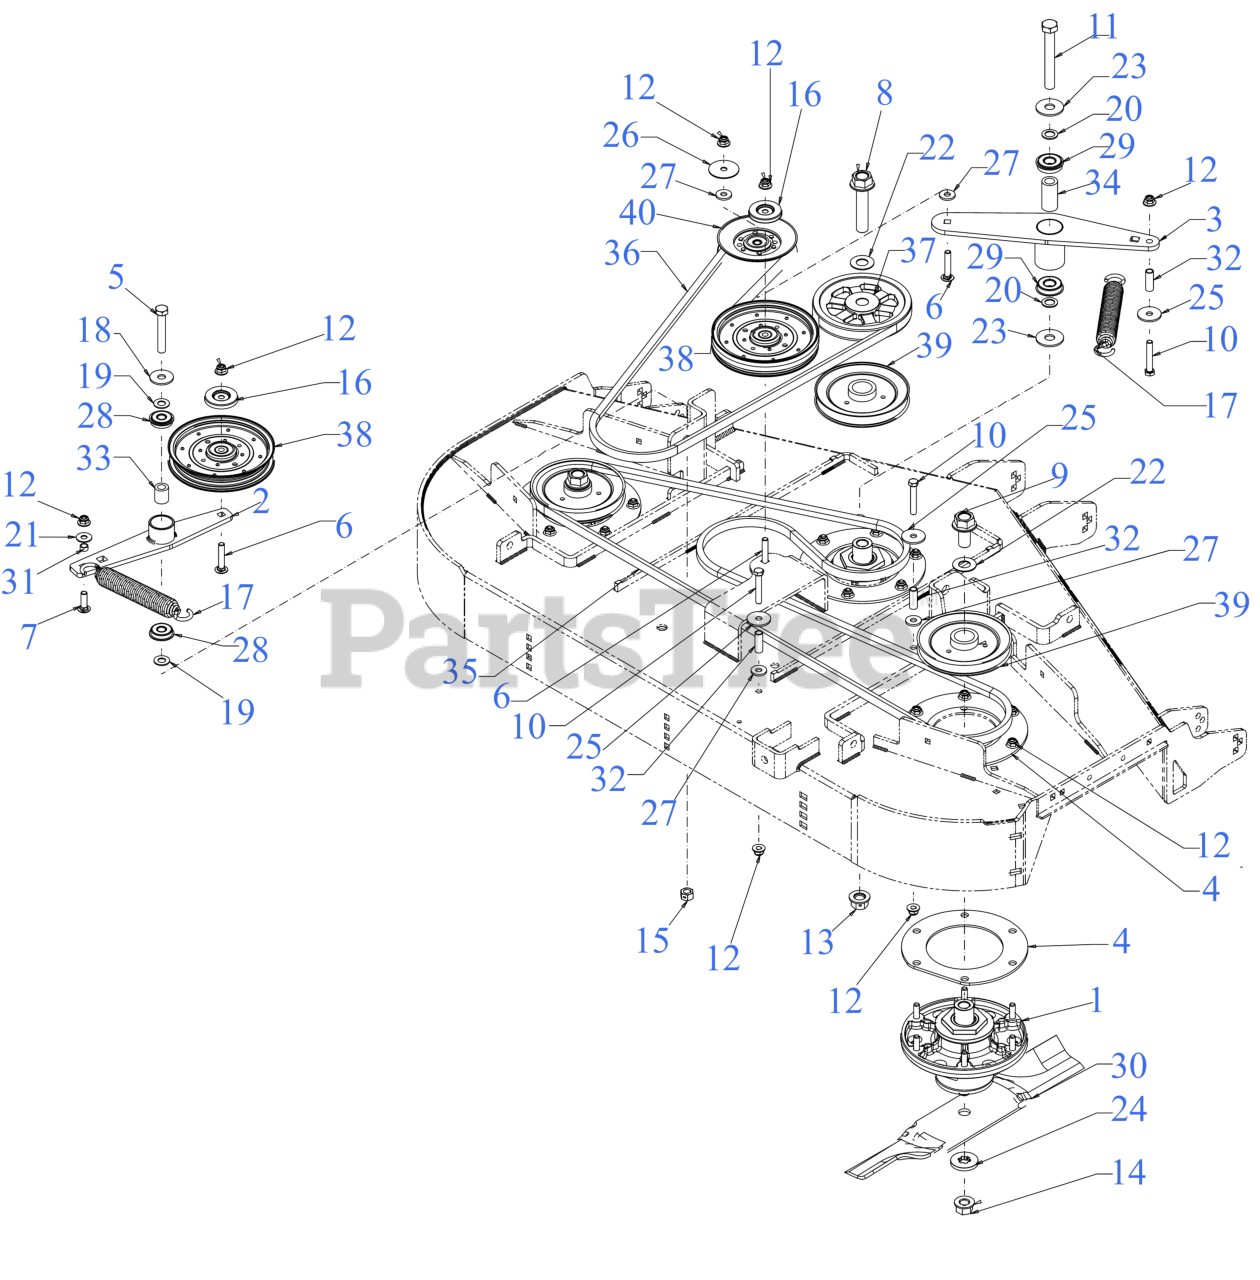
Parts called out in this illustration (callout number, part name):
1	SPINDLE ASSEMBLY
2	IDLER BRACKET
3	IDLER BRACKET
4	SPINDLE SUPPORT BRACKET TOP/BTM
5	SCREW-HEX 1/2-13 x 3.00
6	CARRIAGE BOLT 3/8-16 x 2
7	CARRIAGE BOLT 3/8-16 X1.25 GR5
8	CAP SCREW-HHFLG 3/4-10 X 3.50 GR8
9	CAP SCREW-HHFLG 3/4-10 X 1.50 GR8
10	SCREW 3/8-16 x 2.25 GR5
11	SCREW 5/8-18X4.5 GR5
14	FLANGE NUT - 5/8-18 GDE 8
15	HEX NUT CTR LK 1/2-13
16	PULLEY CAP
17	SPRING 1.25" DIA x 8.5" LONG
18	WASHER .51 x 1.5 x .07
19	FLAT WASHER .510 x .995
20	FLAT WASHER
21	WASHER-.395 x 1.0 x .62
22	FLAT WASHER
23	FLAT WASHER 0.635xX1.755x0.110
24	FLAT WASHER - SPECIAL
25	FLAT WASHER .406X1.500X.105
26	HUB CAP WASHER .406 x 1.92 x .060
27	FLAT WASHER .406ID X1.0 OD
28	ROLLER BEARING .5X1.37X.44
29	BALL BEARING W/RET
30	19" BLADE (HI LIFT)
30	Cub Cadet 54" HI LIFT BLADE SET
30	LOW-LIFT 19"BLADE (54"DECK)
30	BLADE- HI LIFT 19.0 XTREME
30	BLADE-19"MULCH 54"
30	19" XTREME BLADE
33	SPACER 0.51 x 0.88 x 1.00
34	SPACER 0.63 x 1.00 x 2.01
35	BELT-B SECTION 119.45"
36	BELT SEC B x 90.30
37	PULLEY-6.96 OD x .750 ID
38	IDLER PULLEY
39	SPINDLE PULLEY 6"
40	IDLER PULLEY 5.06 OD
